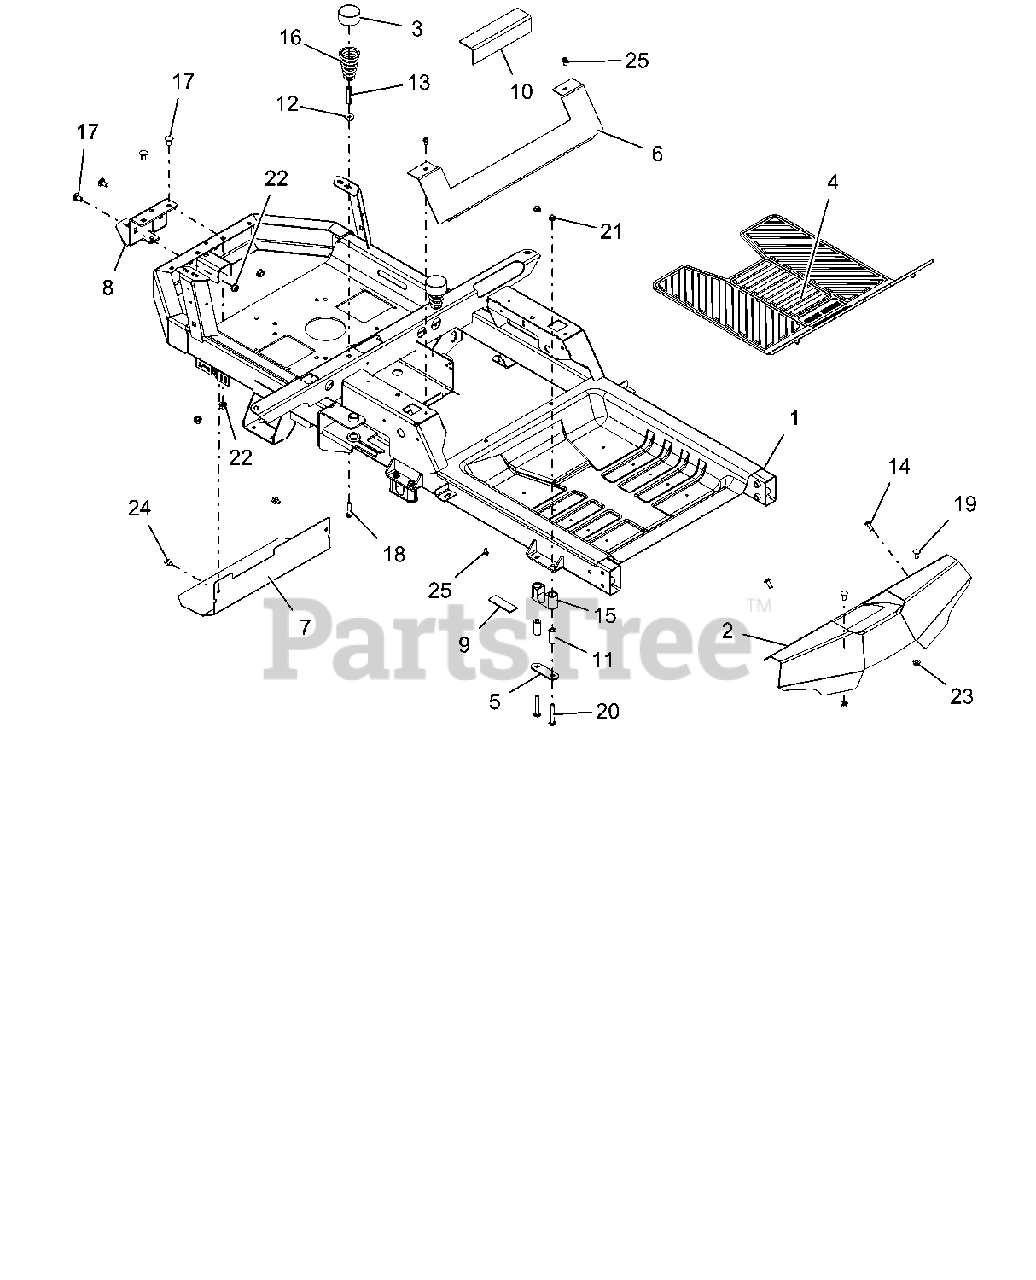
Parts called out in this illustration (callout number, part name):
1	WLDMT, FRAME - 2016 IKON X/XL
2	KIT, FOOTPLATE W/DECAL-IKON XL
3	HUB CAP
4	FLOOR MAT, RUBBER - ARIENS
5	PLATE, BEARING SUPPORT
6	PLATE, SEAT KICK
7	HEAT, SHIELD
8	BRKT, HITCH TONGUE
9	PAD,RBR 1.0"X3.0" W/ADHESIVE
10	PAD, RUBBER-TANK
11	SPACER, .323 X .698 X 1.441
12	WSHR-FL-STL .328X.87X.179 YWZC
13	NUT, COUPLING 5/16-18 X 1 3/4
14	SCR-RDHDSKTAP .31-18 X .75
15	BSHG, DECK LIFT PIVOT
16	SPRING, SEAT
17	@BLT-RDHDSQNK .38-16X.75 G5YZ
18	@BLT-RDHDSQNK .31-18X1.50 G5YZ
19	@BLT-RDHDSQNK .31-18X.75 G5YZ
20	BLT-RDHDSQSHNK .31-18X2.25 YWZ
21	@NUT-LK-CTR-FLG .31-18 YZ GR F
22	@NUT-LK-TOP-FLG .38-16 YWZC
23	@NUT-LK-TOP-FLG .31-18 YWZC
24	@SCR-TAP .31-18X.50 HWH TR YWZ
25	SCR-TAP .25-20X.50 HWH TR YWZ
